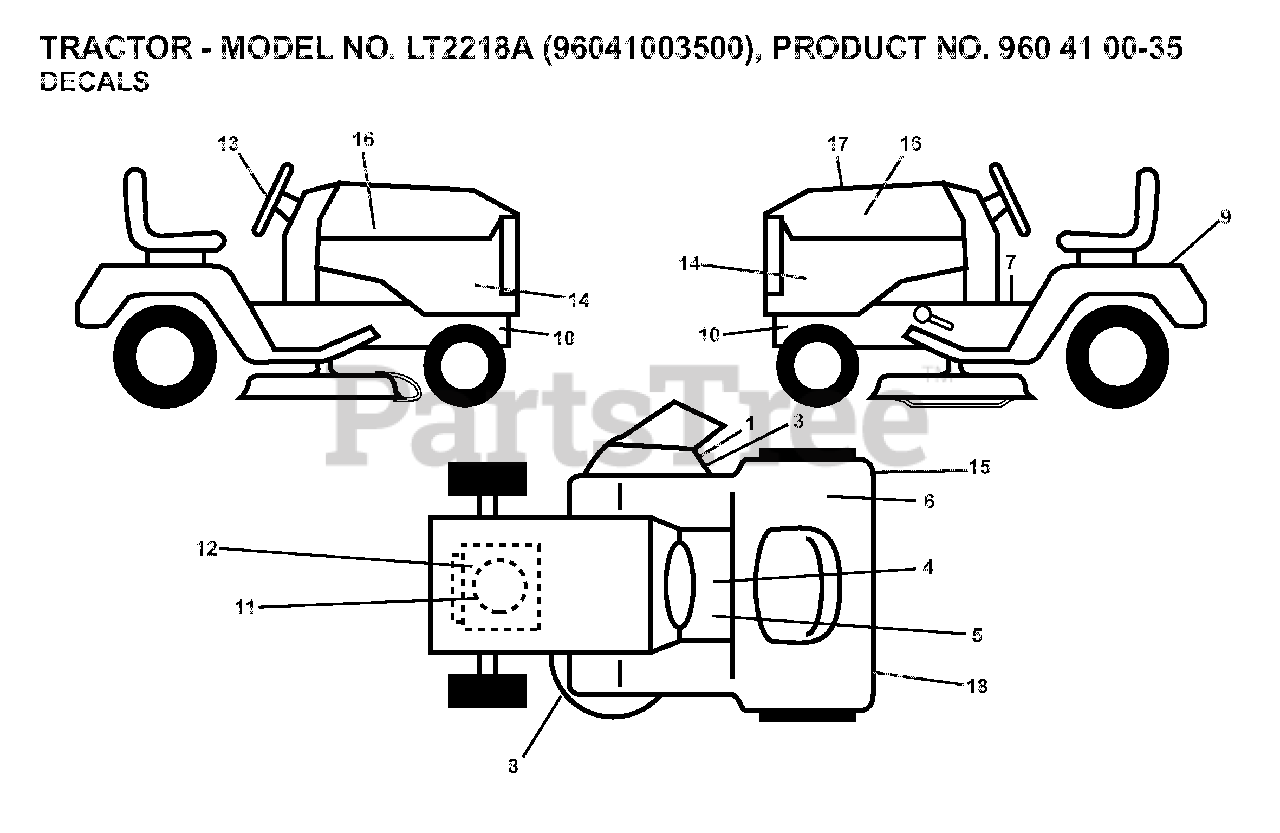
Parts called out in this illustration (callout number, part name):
1	DECAL.INTERNATIONL.CUTFINGER
3	DECAL, DEFLECT WARNING
4	DECAL PARK BRAKE
8	DECAL V BELT SCHEMATIC
9	DECAL BTRY SYMBOLS
